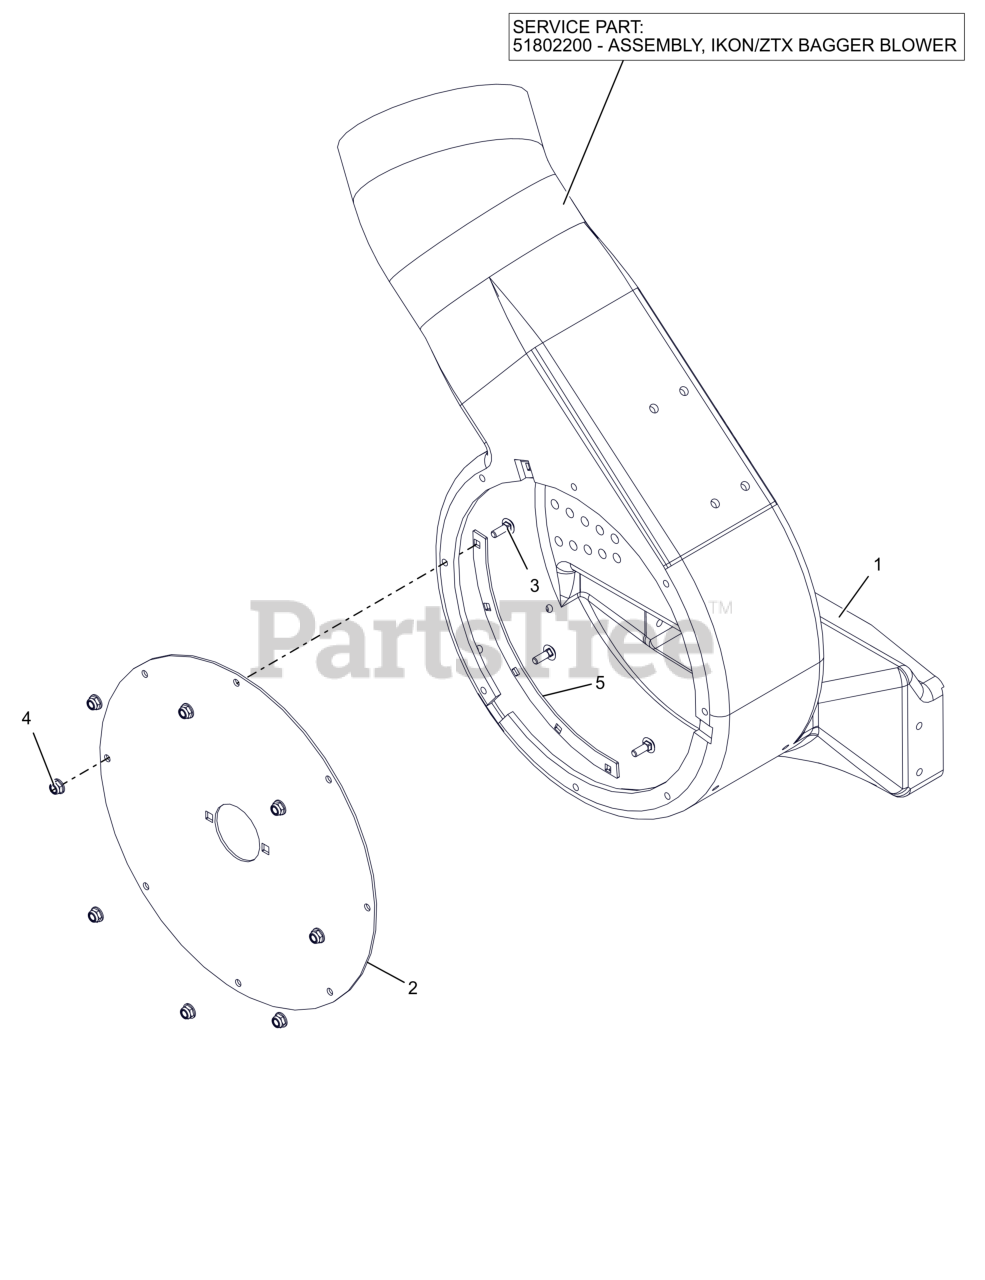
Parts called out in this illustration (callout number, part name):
1	ASM- IKON/ZTX BAGGER BLOWER
1	HOUSING, PLASTIC BLOWER WITH DECALS
2	PLATE, BEARING MOUNT
3	BLT, RHSN .25-20X.750 G5 ZCC
4	NUT,NYL-FLG .25-20 GF ZCC
5	MTG BOLT REINFORCING PLT - BLK
